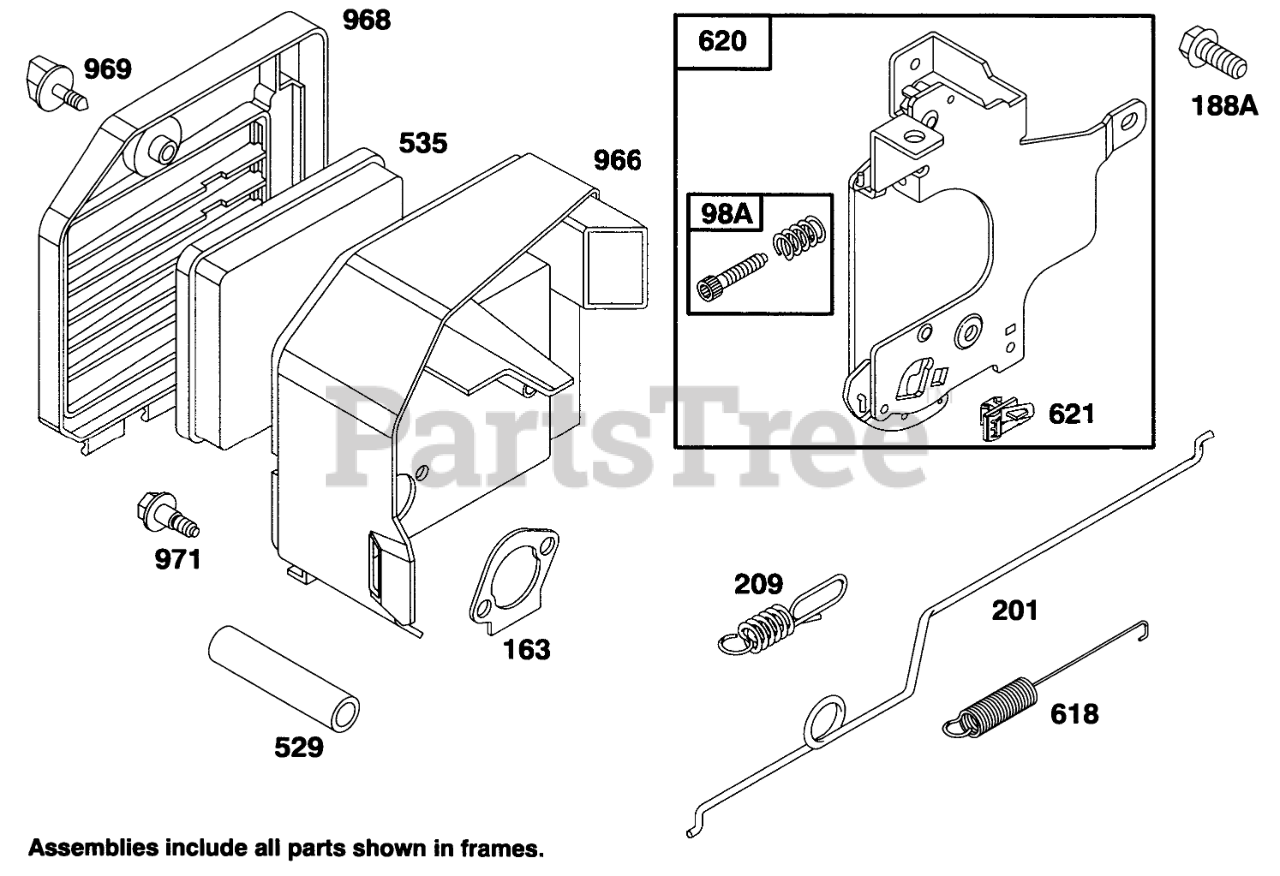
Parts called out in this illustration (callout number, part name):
98A	SPEED ADJUST. SCREW ASM
163	AIR CLEANER GASKET
188A	Screw-Hex Head
201	GOVERNOR LINK
209	GOVERNOR SPRING
529	BREATHER TUBE
535	FILTER ELEMENT
618	RETURN SPRING
620	CARBURETOR BRACKET
621	STOP SWITCH
966	AIR CLEANER BASE
968	AIR CLEANER COVER
969	AIR CLEANER SCREW
971	AIR CLEANER SCREW
